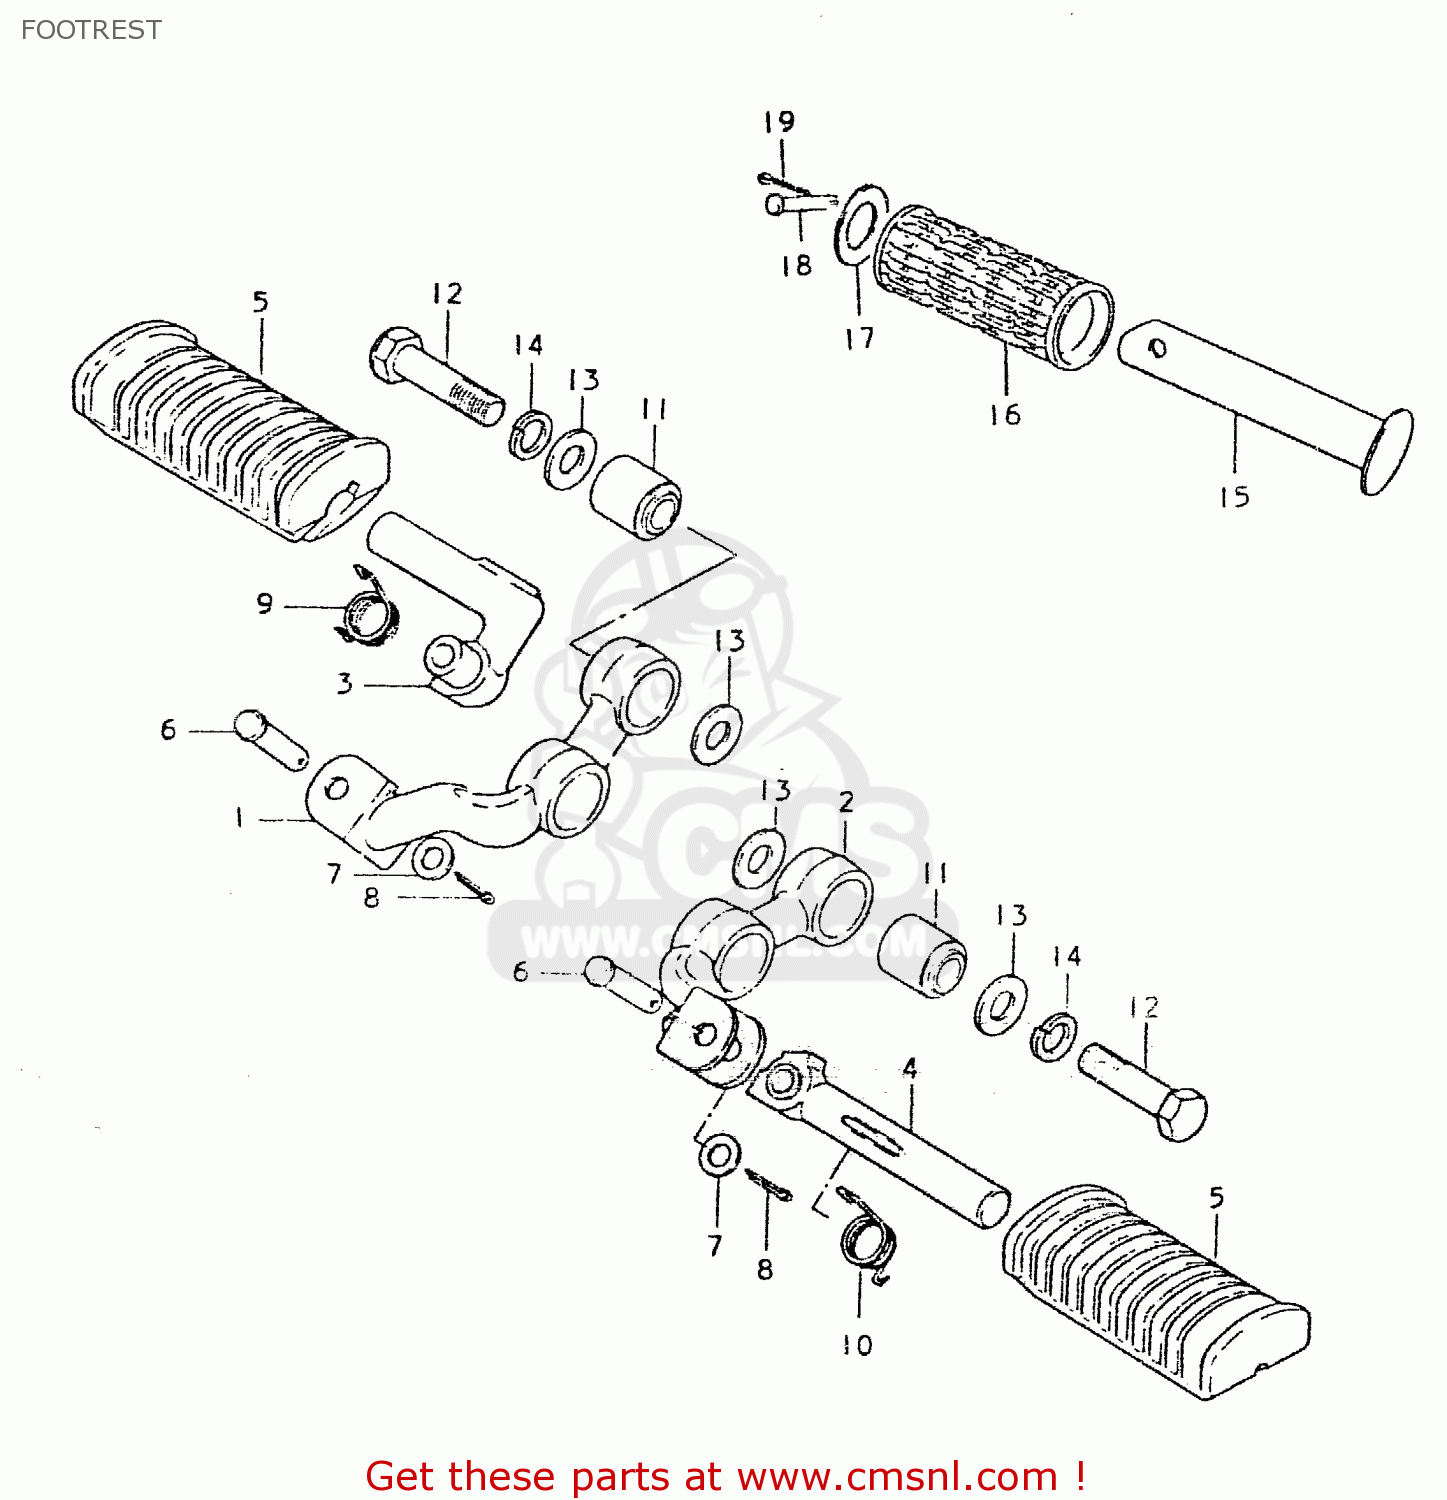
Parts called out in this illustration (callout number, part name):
1	BAR,FRONT FOOTREST,RIGHT
2	BAR,FRONT FOOTREST,LEFT
3	BAR,FRONT FOOTREST,RIGHT NO
4	BAR,FRONT FOOTREST,LEFT NO
5	RUBBER,FR FOOTREST
6	PIN
7	WASHER
8	PIN
9	SPRING
10	SPRING
11	BUSH
12	BOLT
13	WASHER (10.1X21X2.3)
14	LOCK WASHER
15	BAR,PILLION FOOTREST
16	RUBBER,REAR FOOTREST
17	WASHER (19.5X32X2)
18	PIN
19	PIN
